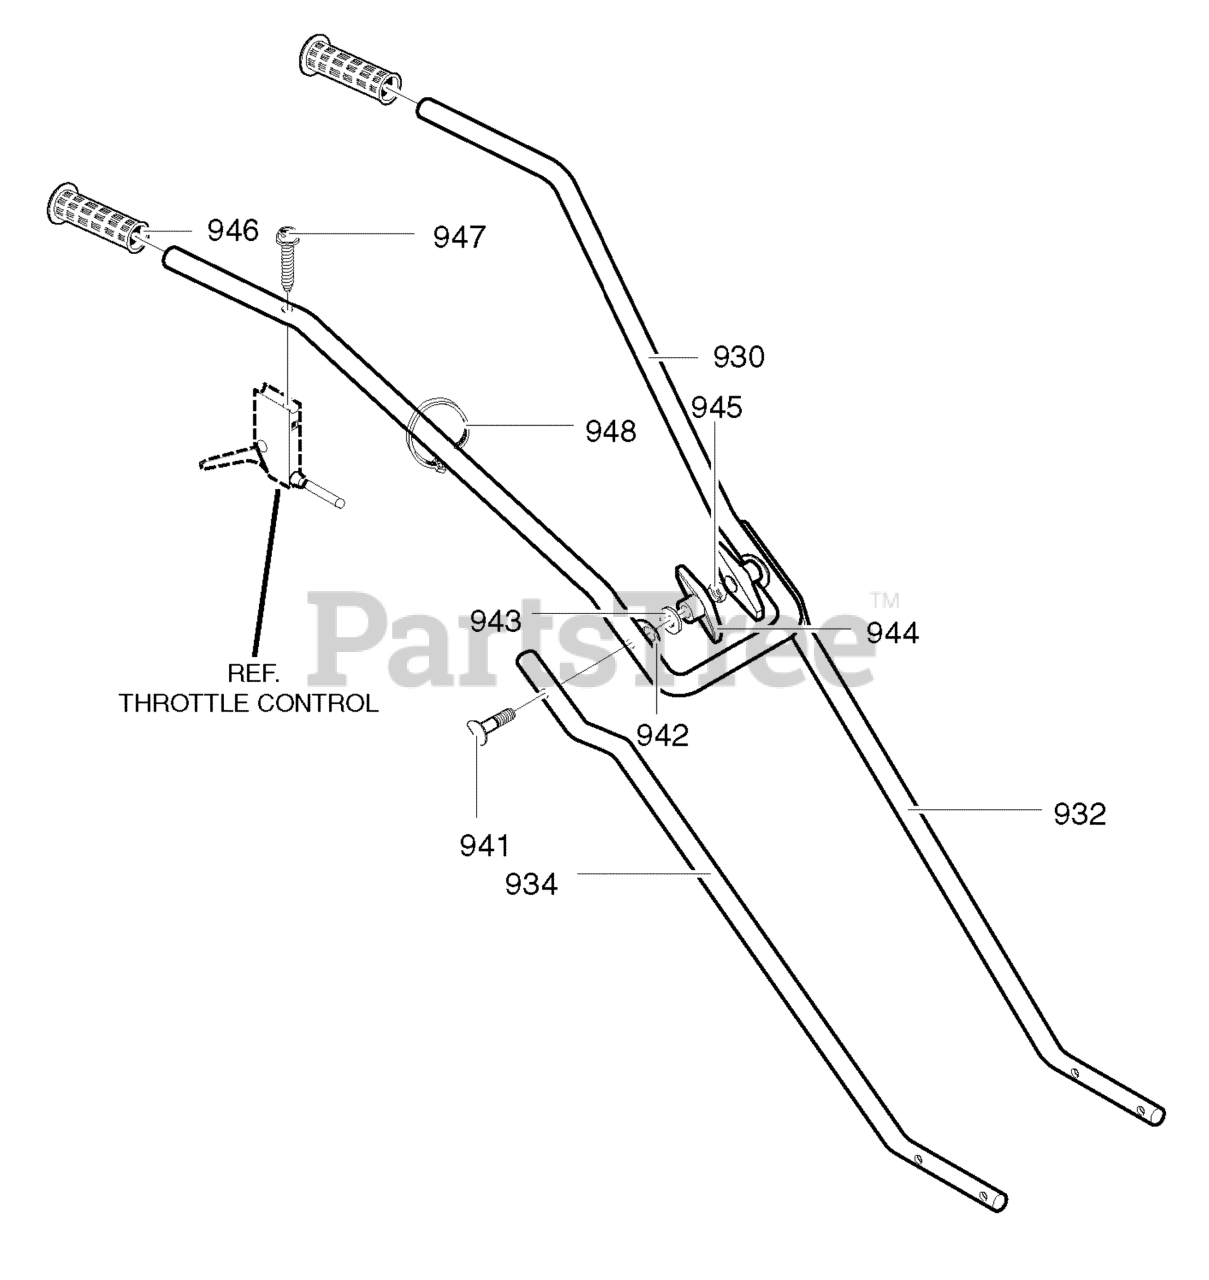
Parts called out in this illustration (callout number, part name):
930	HANDLE, Upper
932	HANDLE, Lower LH
934	HANDLE, Lower RH
941	BOLT 5/16-18x1.63
942	WASHER, Formed
943	FLAT WASHER
945	NUT, 5/16-18
946	GRIP, Hand
948	TIE, Cable
